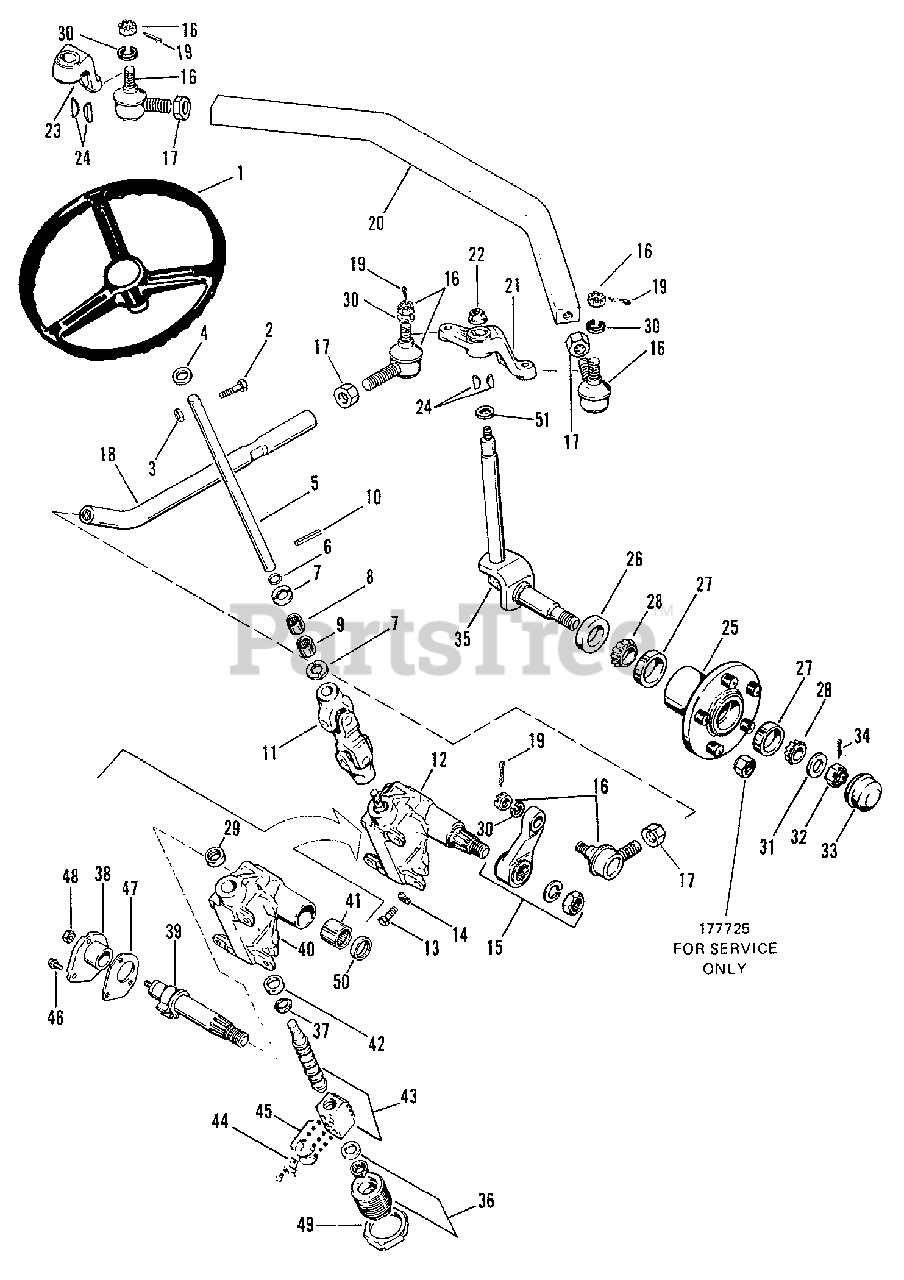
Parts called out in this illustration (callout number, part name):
1	STEERING WHEEL
2	CAPSCREW, Hex, 5/16-18 x 1-1/4" Lg.
3	NUT, Hex, Lock, 5/16-18
5	SHAFT, Steering
6	RING, Retaining
7	WASHER, Thrust
8	BEARING, Roller
9	BEARING, Needle
10	PIN, Roll, 3/8 x 1-1/4" Lg.
11	JOINT, "U"
12	GEAR, Steering Complete
13	CAPSCREW, Hex
14	LOCKWASHER, 7/16"
15	PITMAN ARM
16	JOINT, Ball
17	NUT, Hex, Jam
18	LINK, Drag
19	PIN, Cotter
21	STEERING ARM, R.H.
22	LOCKNUT, Washer Base
23	STEERING ARM, L.H.
25	HUB ASSEMBLY
27	CUP, Bearing
28	CONE, Bearing
30	LOCKWASHER, 1/2"
31	WASHER, Thrust
32	NUT, Slotted
34	PIN, Cotter
35	SPINDLE ASSEMBLY
36	WORM BEARING ADJUSTMENT ASSEMBLY
37	WORM BEARING ASSEMBLY
38	COVER ASSEMBLY
39	PITMAN GEAR ASSEMBLY
40	HOUSING ASSEMBLY
41	BEARING, Needle
42	CUP, Bearing Thrust
43	WORM ASSEMBLY
44	CLAMMP, Ball Return
45	GUIDE, Ball Return
46	BOLT, Hex
50	SEAL, Grease
